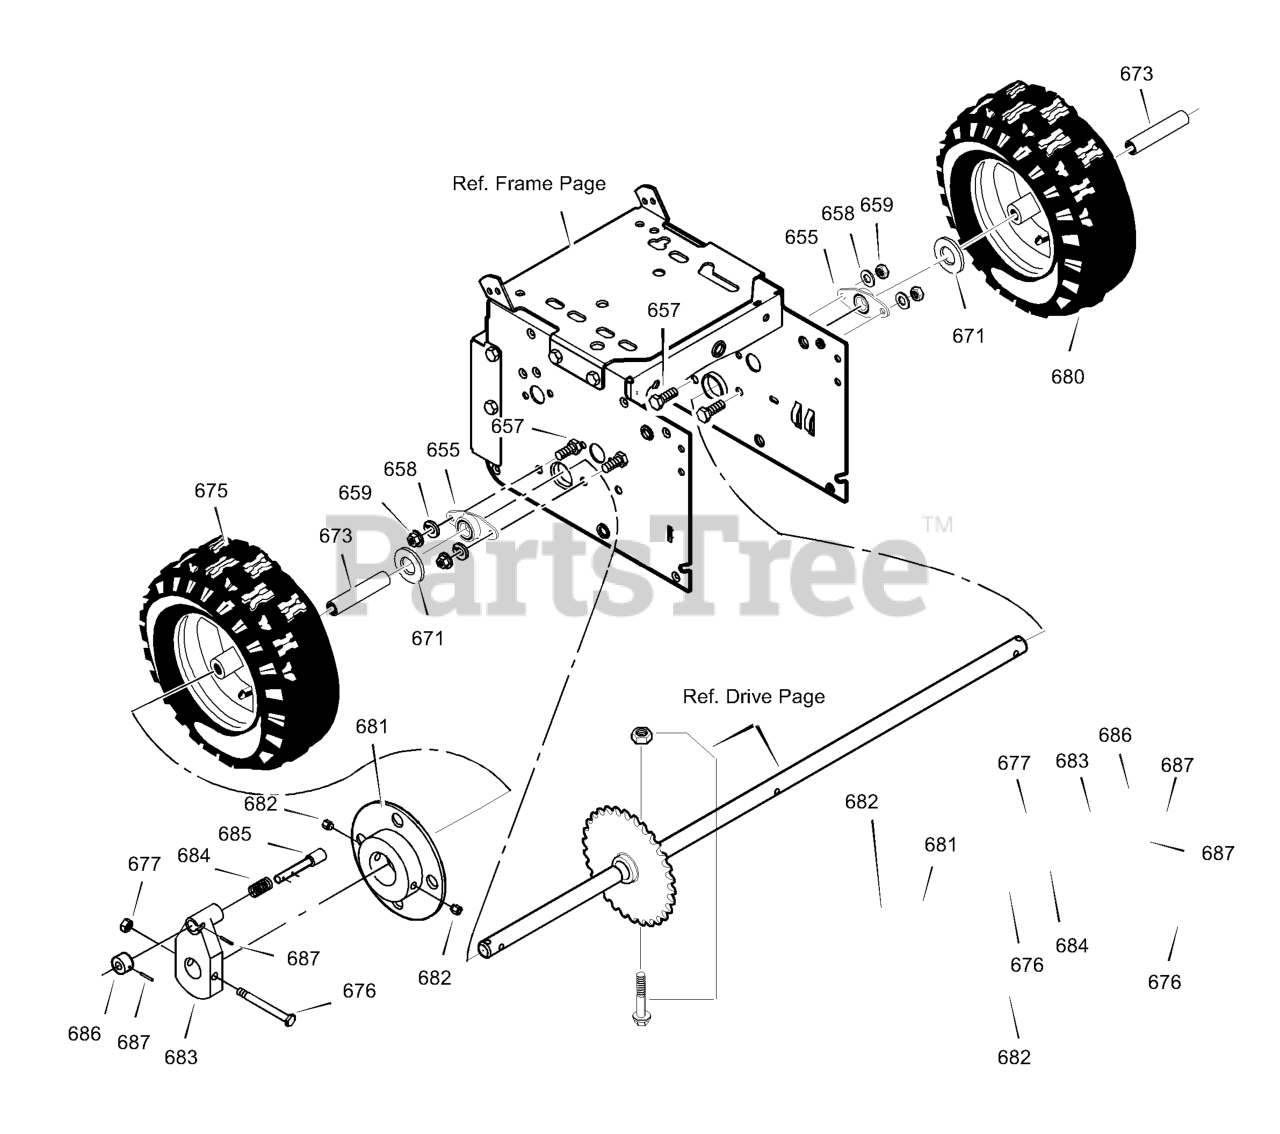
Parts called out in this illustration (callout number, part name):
653	SCREW, 1/4-20X1.75
654	NUT, 1/4-20
655	BEARING & RETAINER ASSY
657	SCREW, 3/8-16 x .75
658	WASHER, SPLTLK
659	NUT, 3/8-163
671	WASHER, FLAT
673	BUSHING, WHEEL
675	TIRE & RIM, RIGHT
676	SCREW, 1/4-20 X 2.25
677	NUT, 1/4-20
680	TIRE & RIM, LEFT
681	DISC, WHEEL
683	HUB, WHEEL LOCK
685	PIN, LOCK
